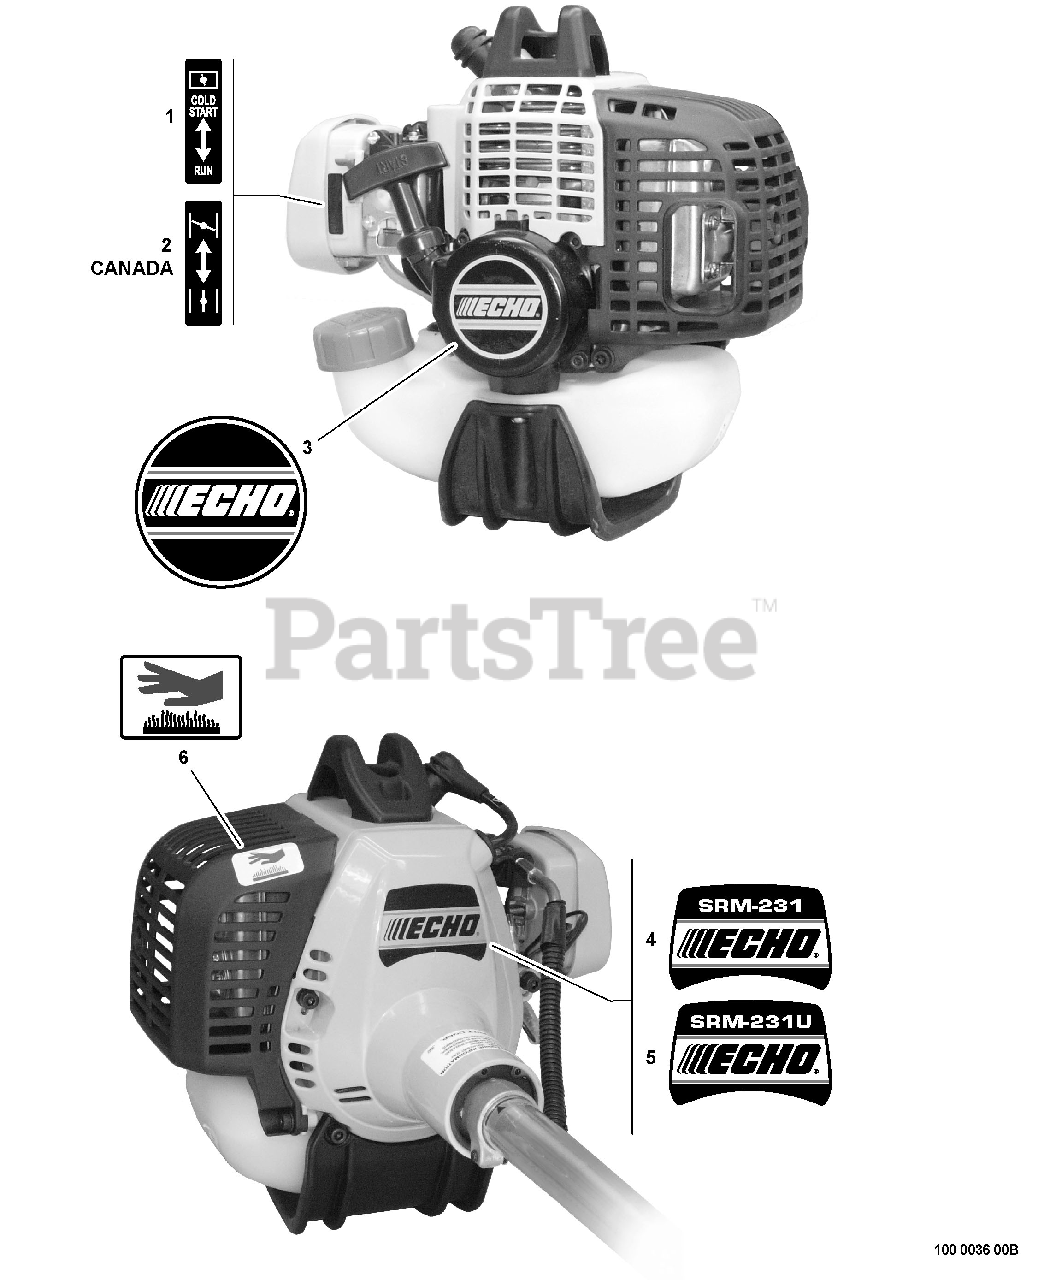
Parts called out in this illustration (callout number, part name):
1	LABEL - CHOKE
2	LABEL - CHOKE
3	LABEL - ECHO
4	LABEL - MODEL SRM-231
5	LABEL - MODEL SRM-231U
6	LABEL - HOT SURFACE
